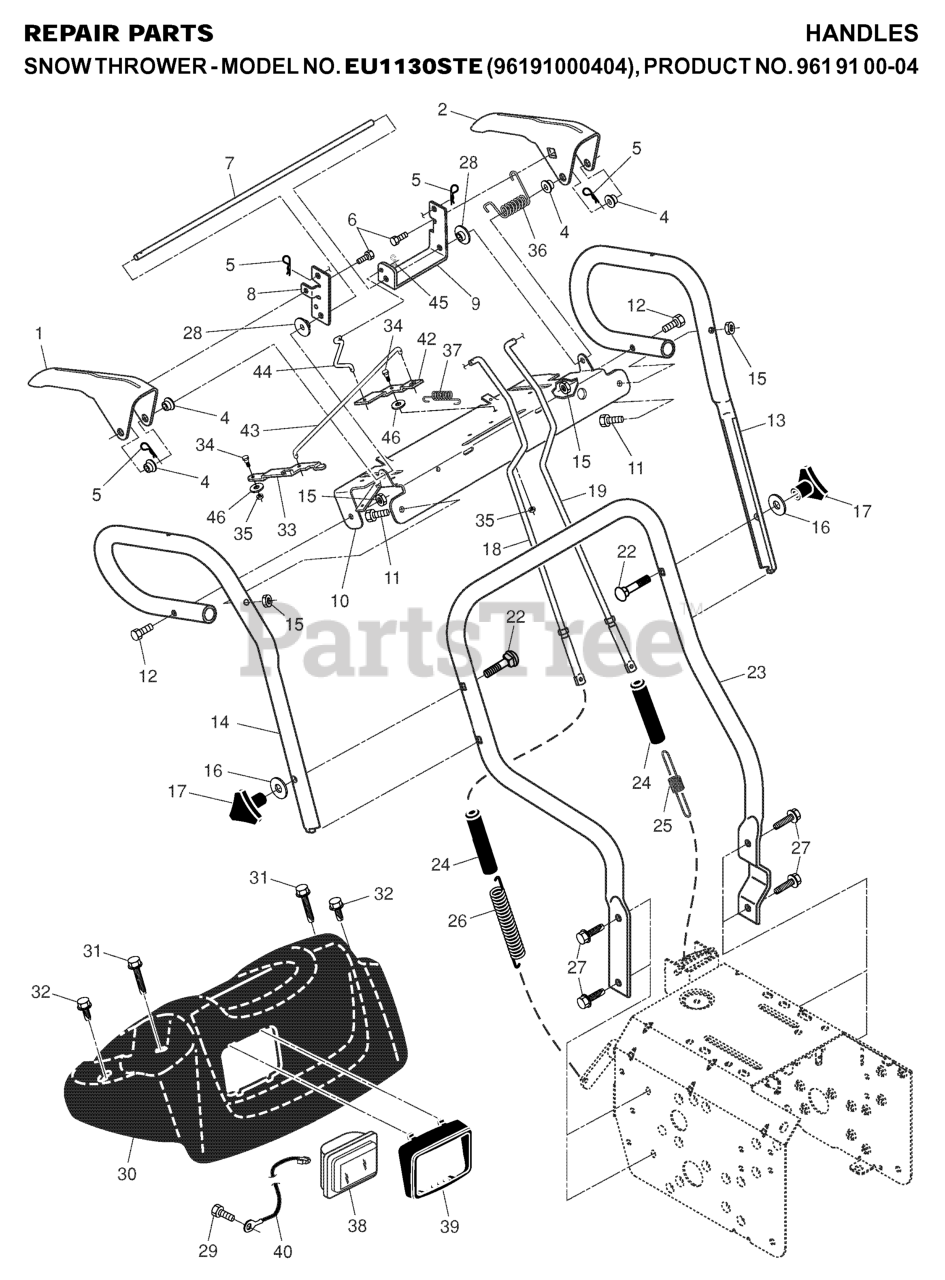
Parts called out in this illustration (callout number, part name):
1	LEVER, AUGER CONTROL, RH
2	LEVER, TRACTION DRIVE CONTROL,
4	BUSHING, FLANGE
5	SPRING RETAINER
7	ROD.INTERLOCK
8	ARM,IMPELLER ROD
9	ARM,TRACTION ROD
10	PANEL.CONTROL
11	HEX BOLT
13	HANDLE TUBE LH
14	HANDLE TUBE RH
15	NUT.LOCK.5/16-18
16	WASHER
17	KNOB.HANDLE.3/8.TRI-POINT.BLAC
18	ROD.ASM.IMPELLER
19	ROD.ASM.TRACTION.
22	BOLT 3/8-16 X 2-1/4
23	TUBE.LOWER.HANDLE.24.BLACK
24	SLEEVE, SPRING
25	SPRING, TRACTION DRIVE
26	SPRING, AUGER CONTROL
27	SCREW 3/8-16X1
28	BUSHING, IDLER PIVOT
29	SCREW.BLOWER.HOUSING.B&S
30	PANEL.CONSOLE.SNOW
31	SCREW, HEX HD TAPPING #10-24 1
32	SCREW, HEX HEAD, TAPPING
33	LATCH.INTERLOCK
34	BOLT, SHOULDER
35	NUT **
36	RP SPRING, TORSION
37	SPRING LATCH
38	HEADLIGHT.HALOGEN.SNOW
39	BEZEL.HEADLIGHT.BLACK
40	HARNESS.WIRE.HALOGEN
42	LEVER.INTERLOCK
43	ROD.LATCH.INTERLOCK
44	ROD.ASM INTERLOCK
45	RETAINER CLIP
46	THRUST WASHER
